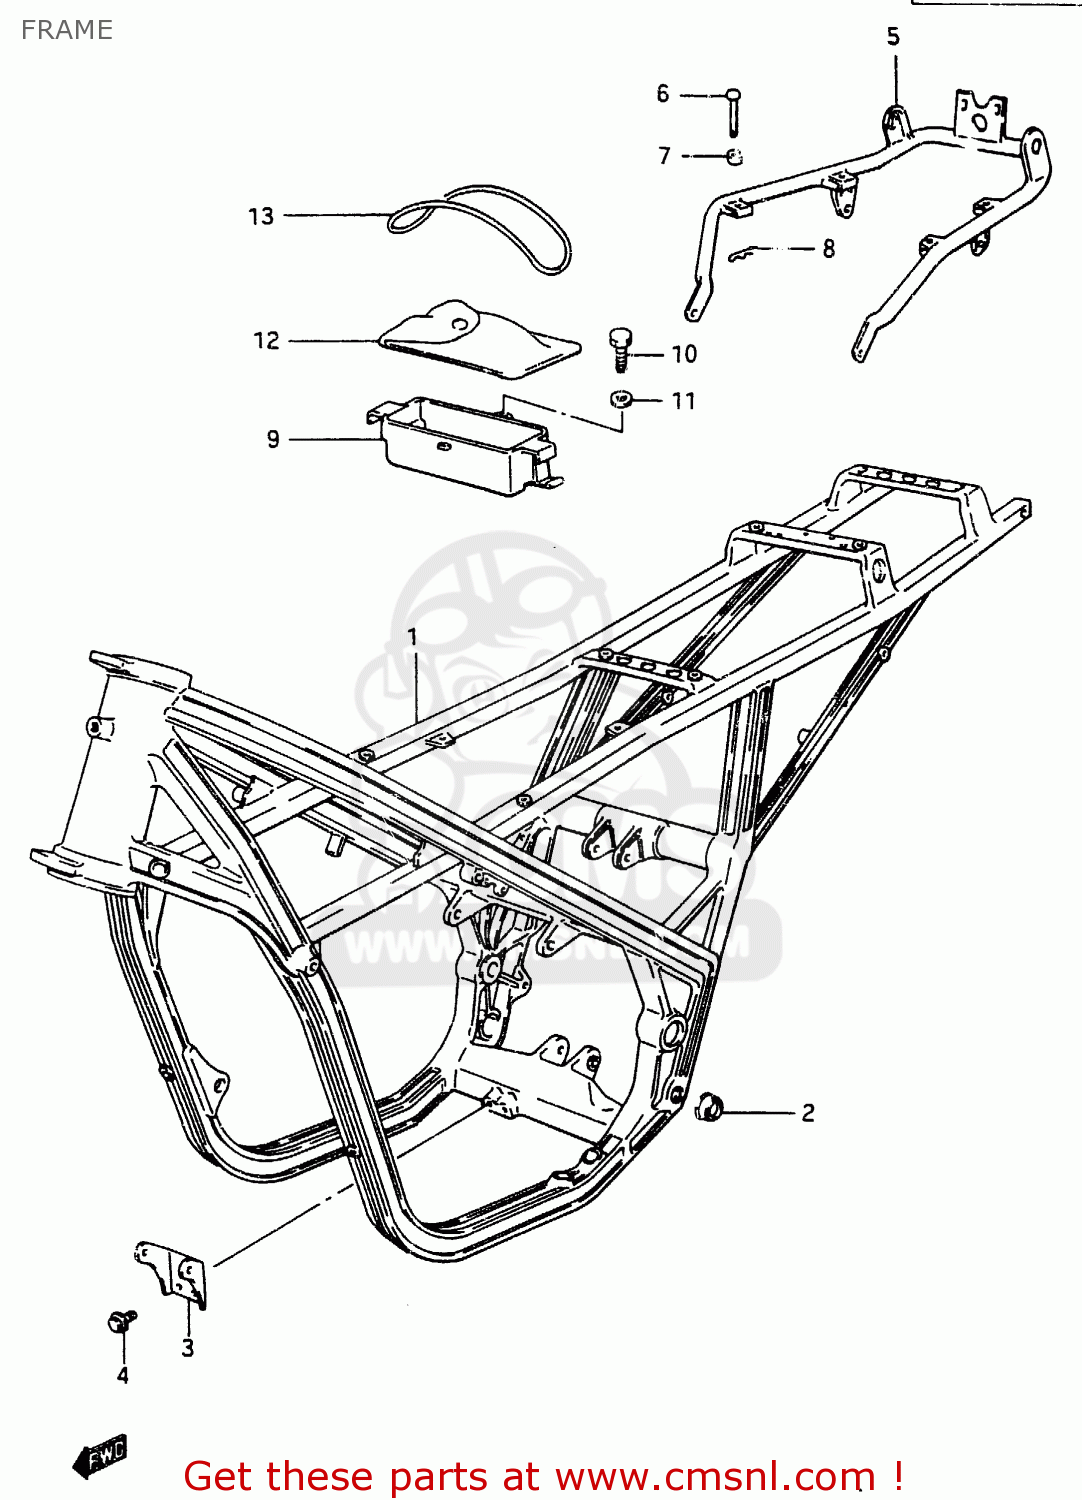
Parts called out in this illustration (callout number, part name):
1	FRAME
2	CAP, FRAME SIDE
3	PLATE, ENGINE MOUNTING
4	BOLT 6X12
5	GRIP, REAR
7	SPACER,GRIP ROD
8	CLIP
9	HOLDER, TOOL
10	BOLT(6X14)
11	WASHER
12	TOOL ASSY
13	O RING(D:3.5,ID:76)
